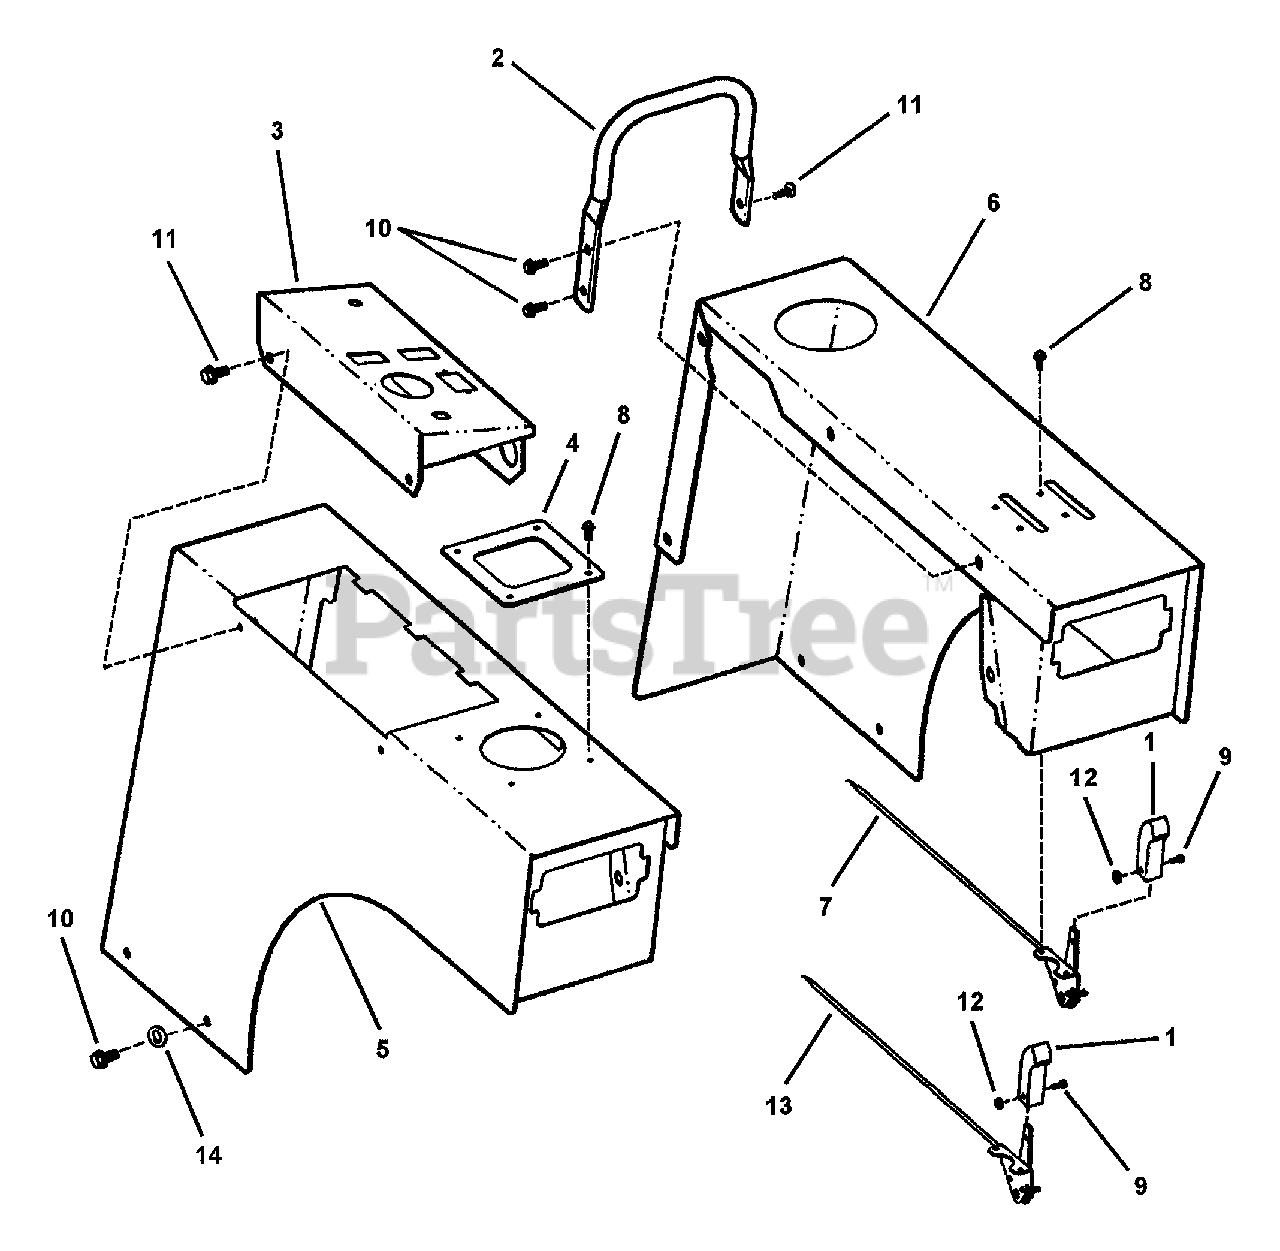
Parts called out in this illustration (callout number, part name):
1	LEVER, Throttle Control
2	HANDLE, 5/8" Tubing
3	PANEL, Console
4	PLATE, Joystick Control
5	FENDER, Right Hand
6	FENDER, Left Hand
7	CABLE, Choke (Kohler) (39.5" Long)
8	SCREW, #10-24 x 1/2" Hex Washer Self-Tap (Torx)
9	SCREW, #8-32 x 3/8" Machine
10	SCREW, 5/16-18 x 5/8" Hex Washer Face Self-tap
11	SCREW, 1/4-20 x 5/8" Hex Flange Lock
12	NUT, #8-32 Hex
13	CABLE, Throttle (Kohler) (39.5" Long)
14	WASHER, 5/16 I.D. Flat
